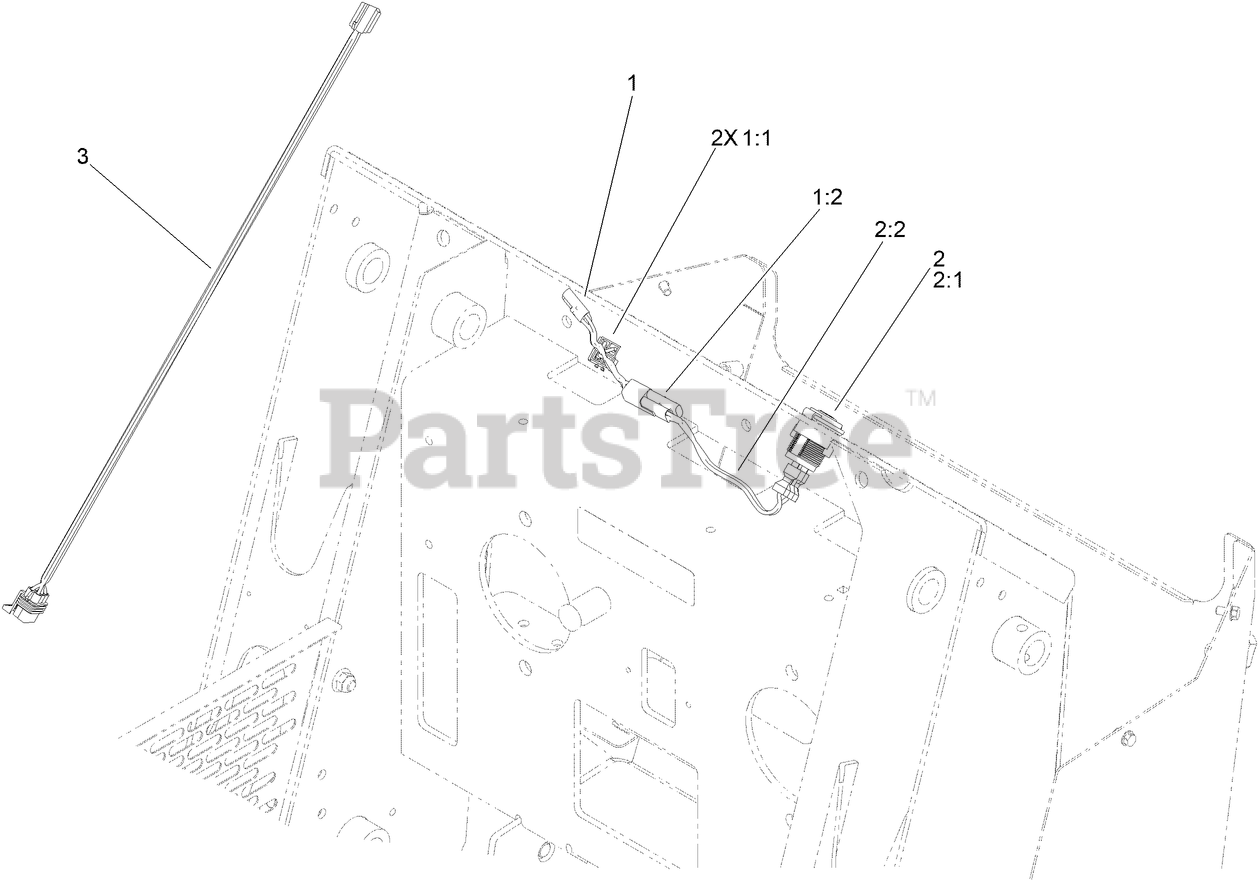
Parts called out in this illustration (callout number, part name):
1	HARNESS-WIRE, SPLITTER
1:1	FUSE-BLADE, 10 AMP
1:2	CAP-PLUG
2	ELEC ACCESSORY PORT, GRANDSTAND MOWER
2:1	RECEPTACLE-12V
2:2	HARNESS, RECEPTACLE 12V
